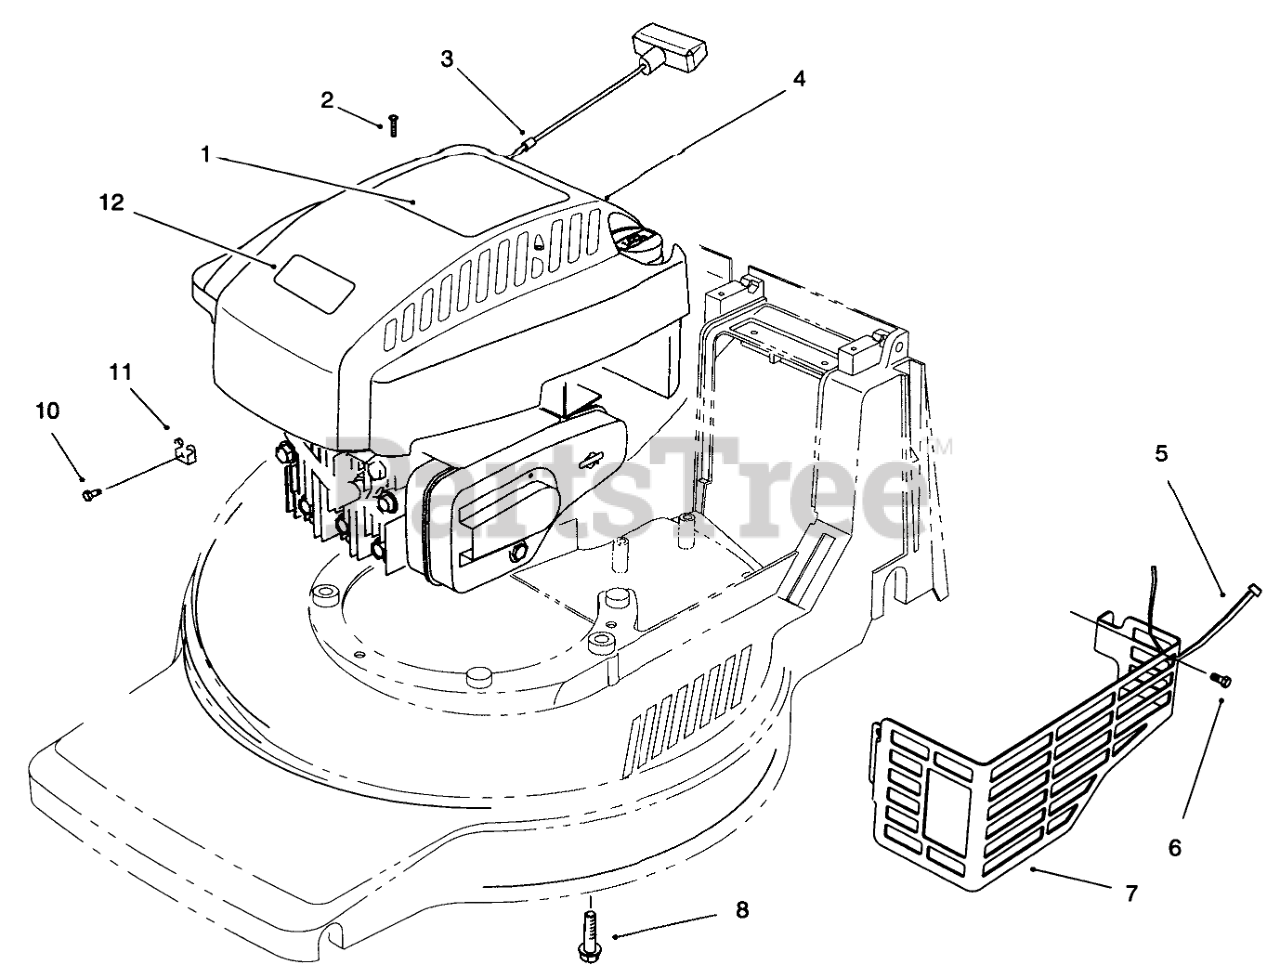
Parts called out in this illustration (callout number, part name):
1	DECAL - SHROUD
2	SCREW-PPH
3	STOP-ROPE
4	SHROUD-ENGINE
5	TIE-CABLE
6	SCREW-HWH
7	SHIELD-MUFFLER
8	SCREW-HWH
10	SCREW-CLAMP
11	CLAMP-CASING
12	PLATE-LOGO
